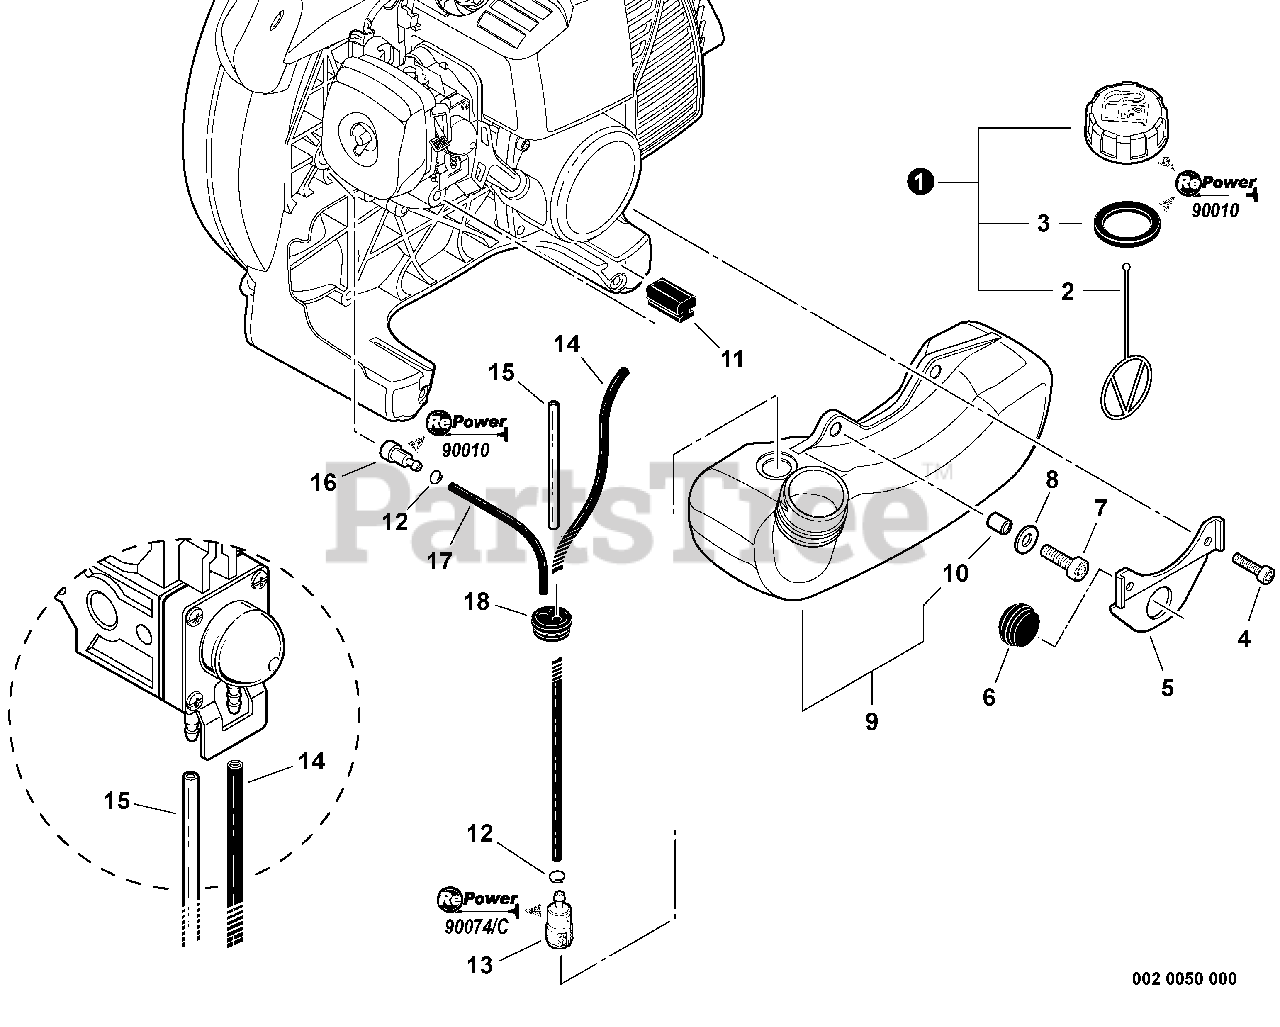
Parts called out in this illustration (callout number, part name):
1	CAP ASSY, FUEL
2	CONNECTOR, CAP L= 100 MM
3	GASKET, FUEL CAP
4	BOLT, TORX 4×16
5	BRACKET, FUEL TANK
6	CUSHION
7	BOLT, TORX 5×16
8	WASHER 5.5×12×0.8
9	TANK ASSY, FUEL
10	SPACER 6.2×7.8×6
12	CLIP 6 MM
13	FILTER, FUEL
14	PIPE, FUEL 3×5×210 BLACK
15	PIPE, FUEL 3×6×85 CLEAR
16	VENT ASSY
17	PIPE, FUEL 3×5×80 BLACK
18	GROMMET, FUEL
19	CAP/VENT KIT - REPOWER
20	TUNE-UP KIT - REPOWER
